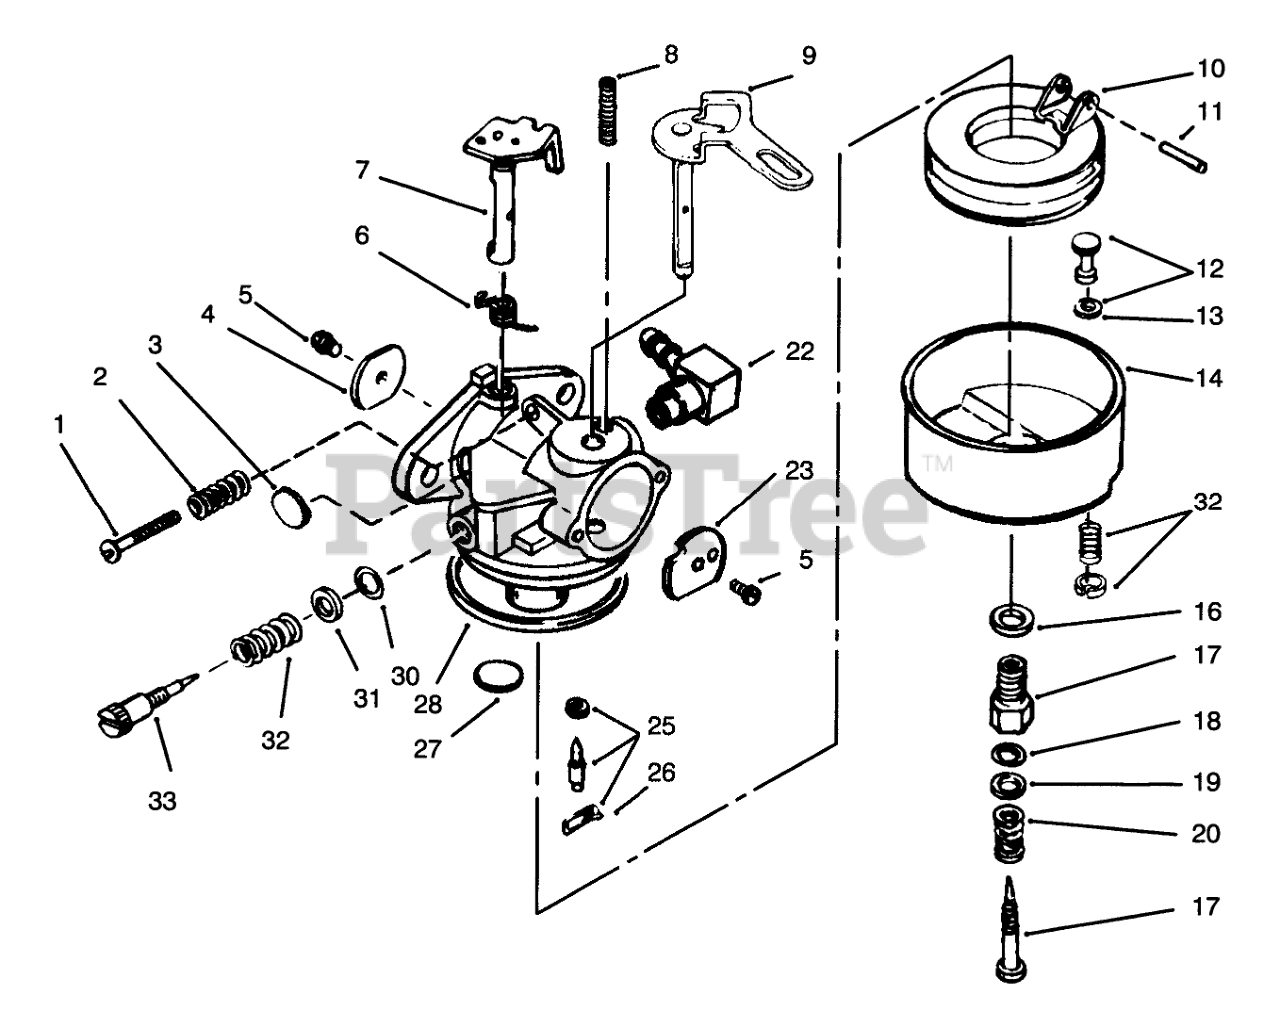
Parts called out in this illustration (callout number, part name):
1	Screw-Throttle Crack Screw / Idle Speed
2	Spring-Tension
3	Plug-Welch, Idle Mixture Well
4	Shutter-Throttle
5	Screw-Shutter
6	Spring-Return, Throttle
7	Throttle Shaft and Lever ASM
8	Spring-Positioning, Choke
9	Choke Shaft and Lever Asm
10	Float
11	Shaft-Float
12	Drain Assembly-Bowl (Incl. Ref. #13)
13	Gasket-Plunger, Drain
14	Bowl-Assembly (Incl. Ref. #12 & 13)
16	Washer-Bowl Nut
17	Screw Adjustment Assembly (Incl. Ref. #16-20)
18	"O"Ring
22	Fitting-Fuel
23	Shutter-choke
25	Inlet Needle-Seat & Clip (Incl. Ref. #26)
26	Clip-Spring
27	Plug-Welch, Atmospheric Vent
29	O Ring-Bowl, Float
30	"O"Ring
32	Spring-Tension
33	Screw-Idle
